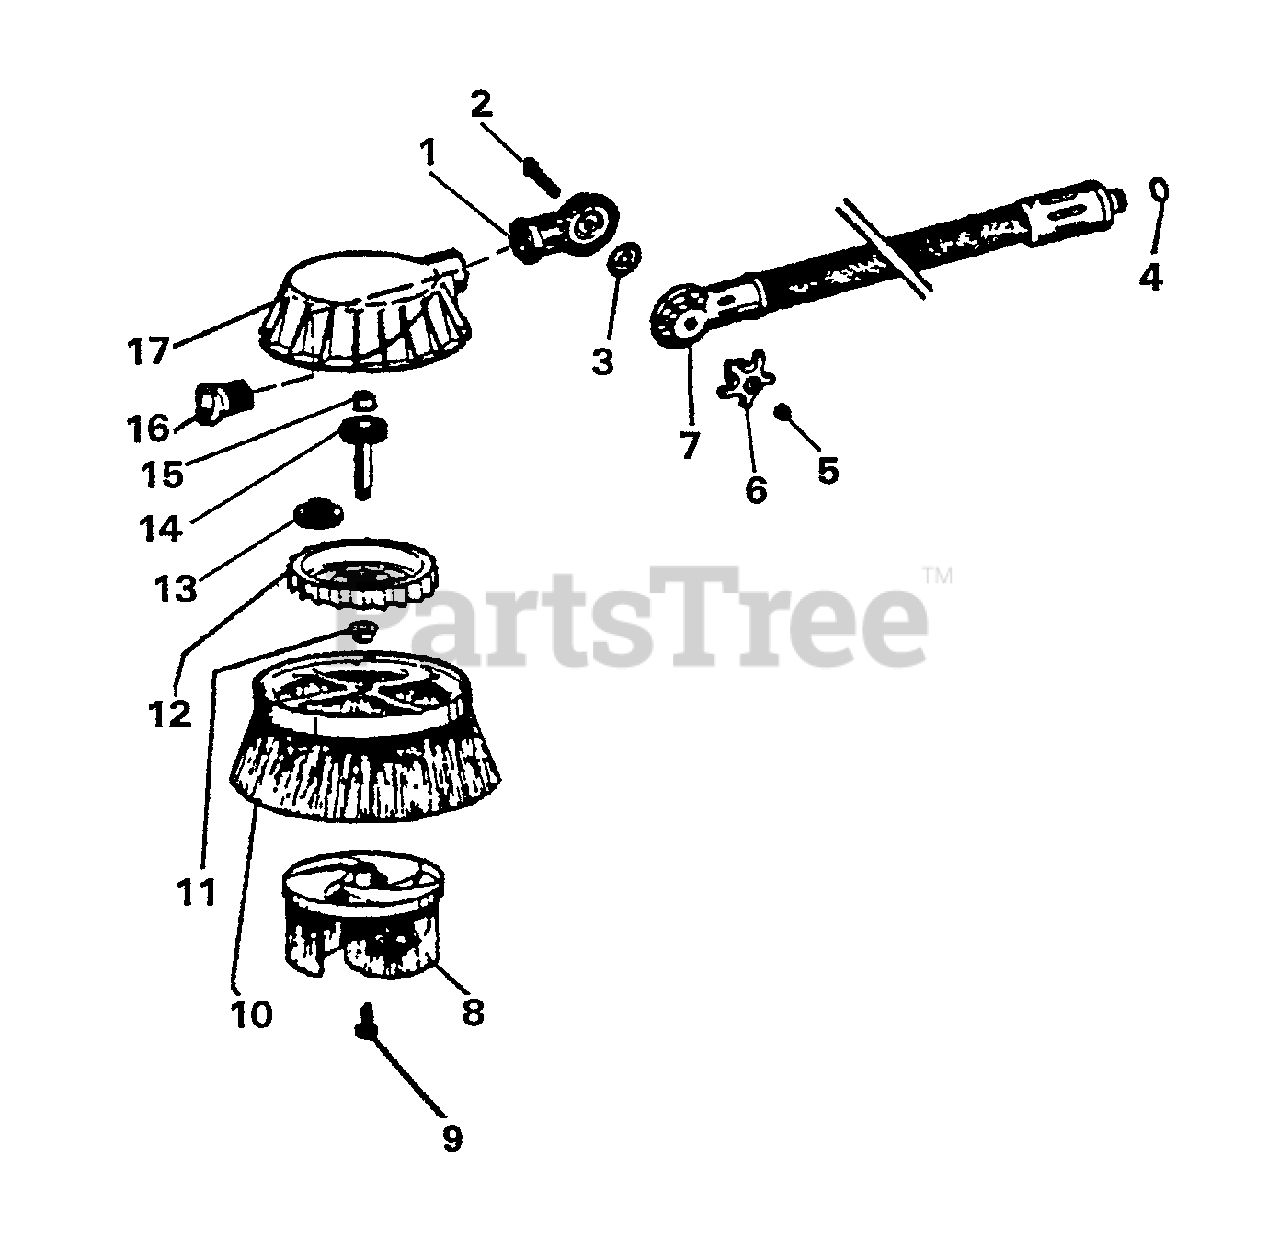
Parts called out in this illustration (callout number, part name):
1	CONNECTOR, ADJUSTABLE
2	SCREW - 6X40
3	GASKET, CONNECTOR
4	O-RING - .359 X .103
5	NUT - 6
6	KNOB, REGULATING
7	HAND GRIP, BRUSH
8	BRUSH, ROTATING
9	SCREW - 6X13
10	BRUSH, FIXED
11	BUSHING
12	TURBINE
13	GEAR
14	GEAR - SHAFT
15	BUSHING
16	NOZZLE, 3.85
17	COVER
